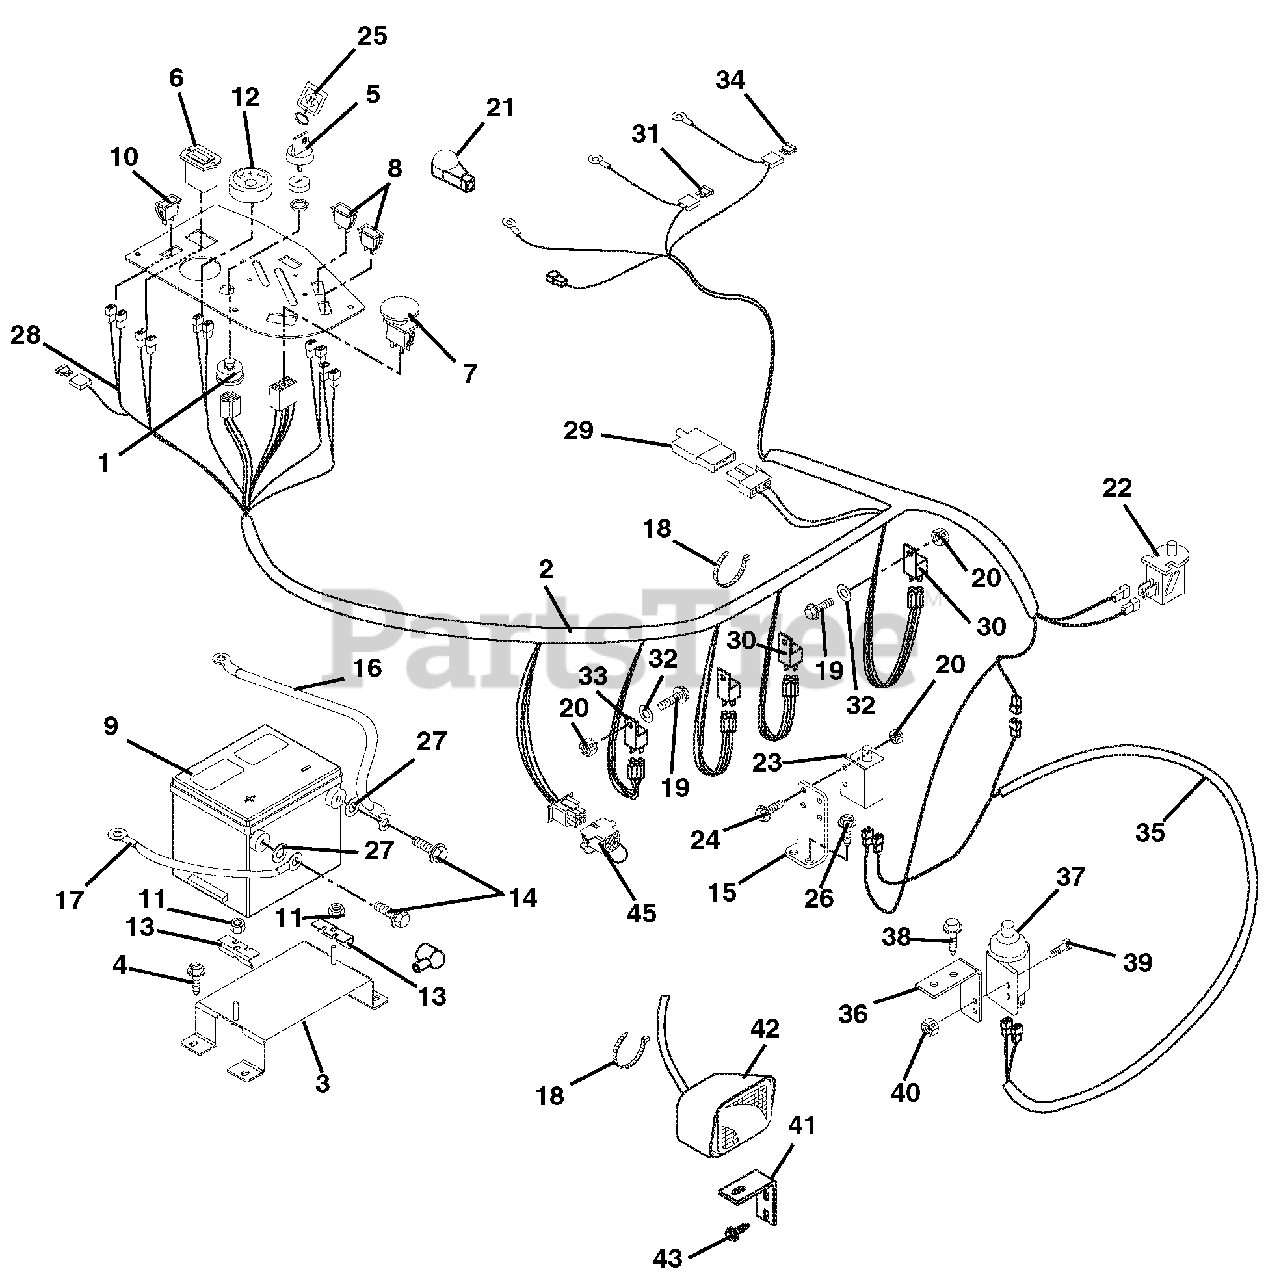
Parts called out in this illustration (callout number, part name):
1	Switch, Ignition (Diesel)
2	Harness, Wiring (Diesel)
3	Weldment, Battery Support
4	Screw-Tapping .38-16 x .75 Hex Washer Head
5	Key-with Cap
6	Hour Meter
7	Switch-Clutch With Retainer Ring
8	Light-Indicator Kit
9	Battery with Tube
10	Switch, Light
11	Nut-Locking-Top-Flange .31-18
12	Gauge, Temperature
13	Bracket, Battery Hold-Down
14	Bolt-Hex .25-20 x .75 Grade 5
15	Mount, Safety Switch
16	Positive Cable
17	Cable, Negative Battery
18	Cable Tie
19	Screw-Machine 10-24 x .75 Hex Washer Head
20	Nut-Locking-Nylon 10-24 With Insert
21	Battery Terminal Boot, Red
22	Switch, Snap Mounting (N.O.) (Included with Seat)
23	Switch-Single Pole
24	Screw-Machine 10-24 x .75 Hex Washer Head
25	Key Chain
26	Screw-Tapping .25-20 x .50 Hex Washer Head
27	Washer-Flat-Steel .406 x 1.00 x .188
28	Fuse, 15 Amp
29	Diode, Connector Shell
30	Relay (Included with Harness)
31	Fuse, 30 Amp (Included with Harness)
32	Washer-Flat-Steel .25 x .562 x .049
34	Fuse, 50 AMP (Maxi Fuse) (Included with Harness)
35	Harness, Wire Adapter CE
36	Mount- Switch
37	Switch-Single Pole (N.O.) with Cover
38	Screw-Tapping .31-18 x .50 Hex Washer Head
39	Screw-Machine 10-24 x .75 Hex Washer Head
40	Nut-Locking-Nylon 10-24 with Insert
41	Bracket, Headlight Mounting
42	Headlight
43	Screw-Tapping .38-16 x .50 Hex Washer Head
44	Boot, Eyelet Terminal
45	Harness, Jumper (EYE-Q)
